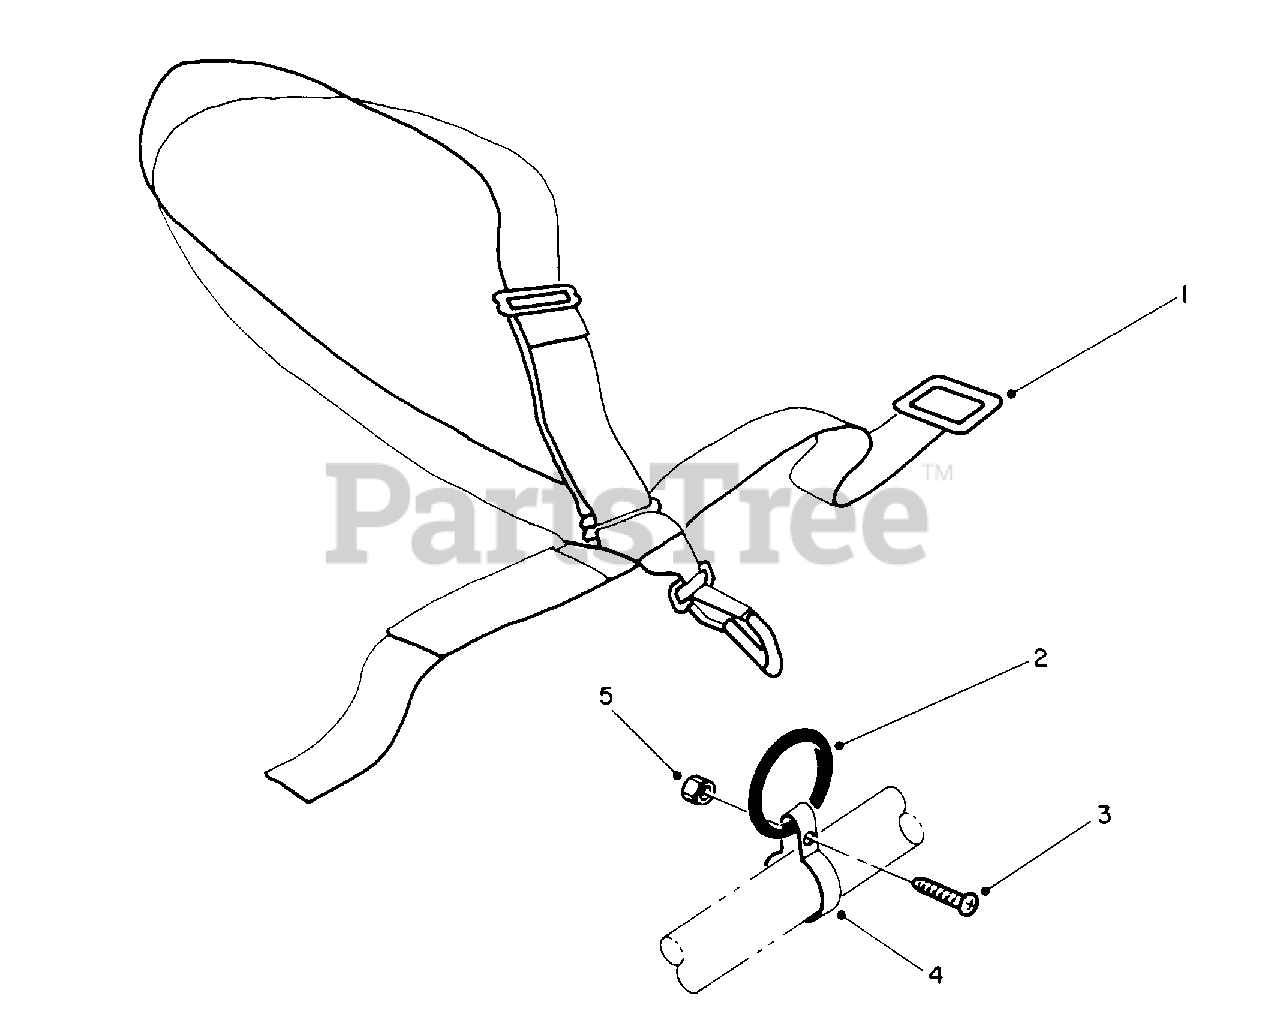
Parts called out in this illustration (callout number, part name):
1	Deluxe Harness
2	Ring
3	Screw
4	Clamp
5	Nut
